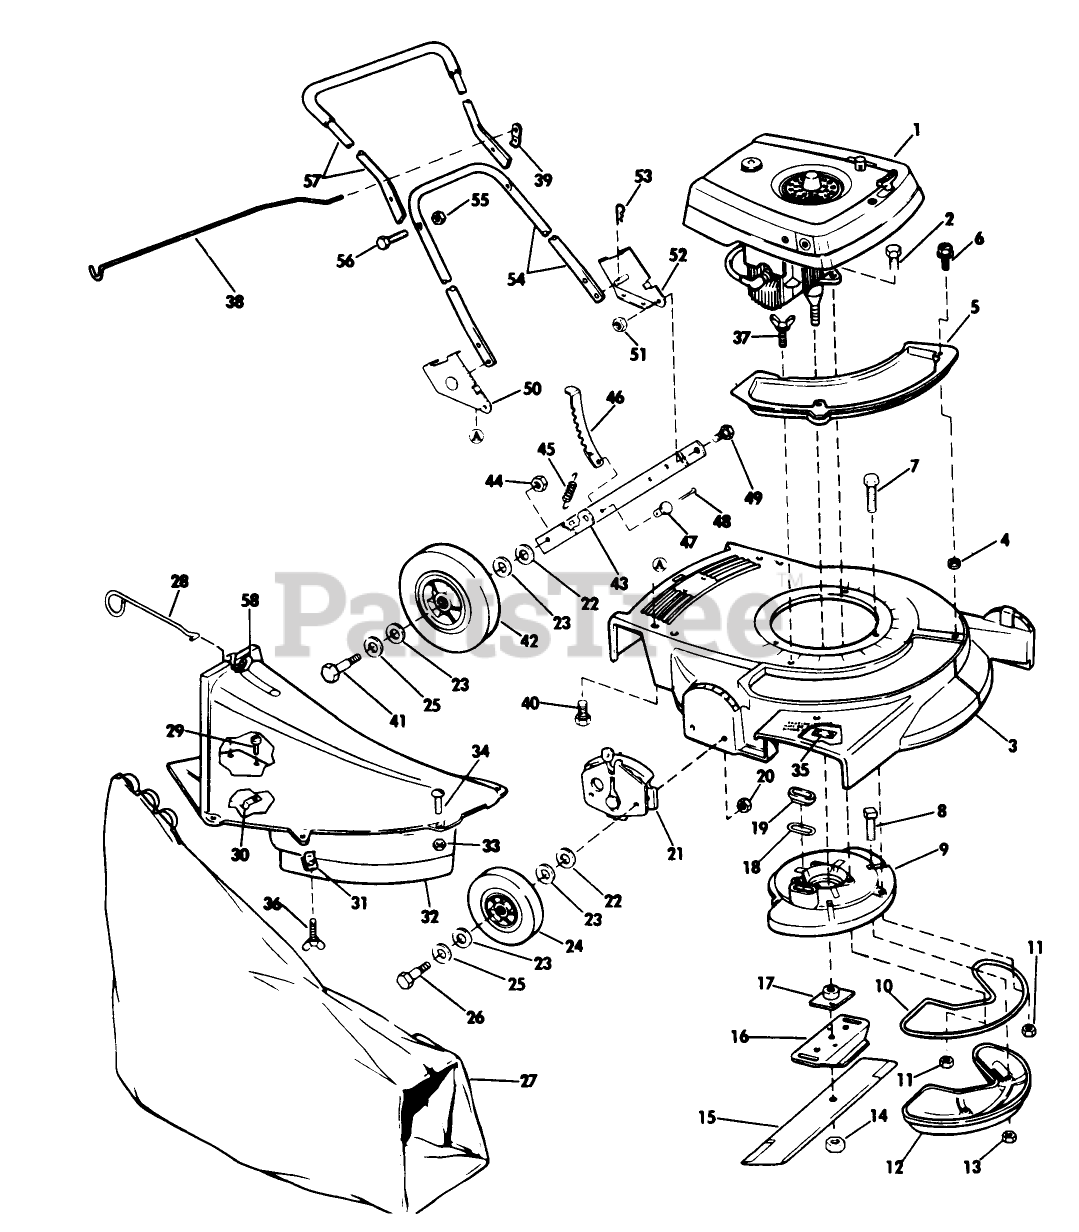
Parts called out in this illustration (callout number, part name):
6	SCREW SEMS TRM HEX HD
7	SCREW
11	NUT
13	LOCKNUT E
14	NUT-BLADE
17	PLATE AND COLLAR ASM
18	GASKET S
19	SLEEVE
20	NUT
22	WASHER WROUGHT
23	WASHER
25	SPACER
26	BOLT WHEEL
27	89802 LB WHOLE GOODS
31	SPEED NUT ARDEN
32	Skirt Assembly
33	NUT S
36	SCREW
38	ROD & CLIP
41	BOLT
44	LOCKNUT
45	SPRING N.A.S
49	BOLT-SHOULDER
51	NUT
53	HAIR PIN
56	SCREW
